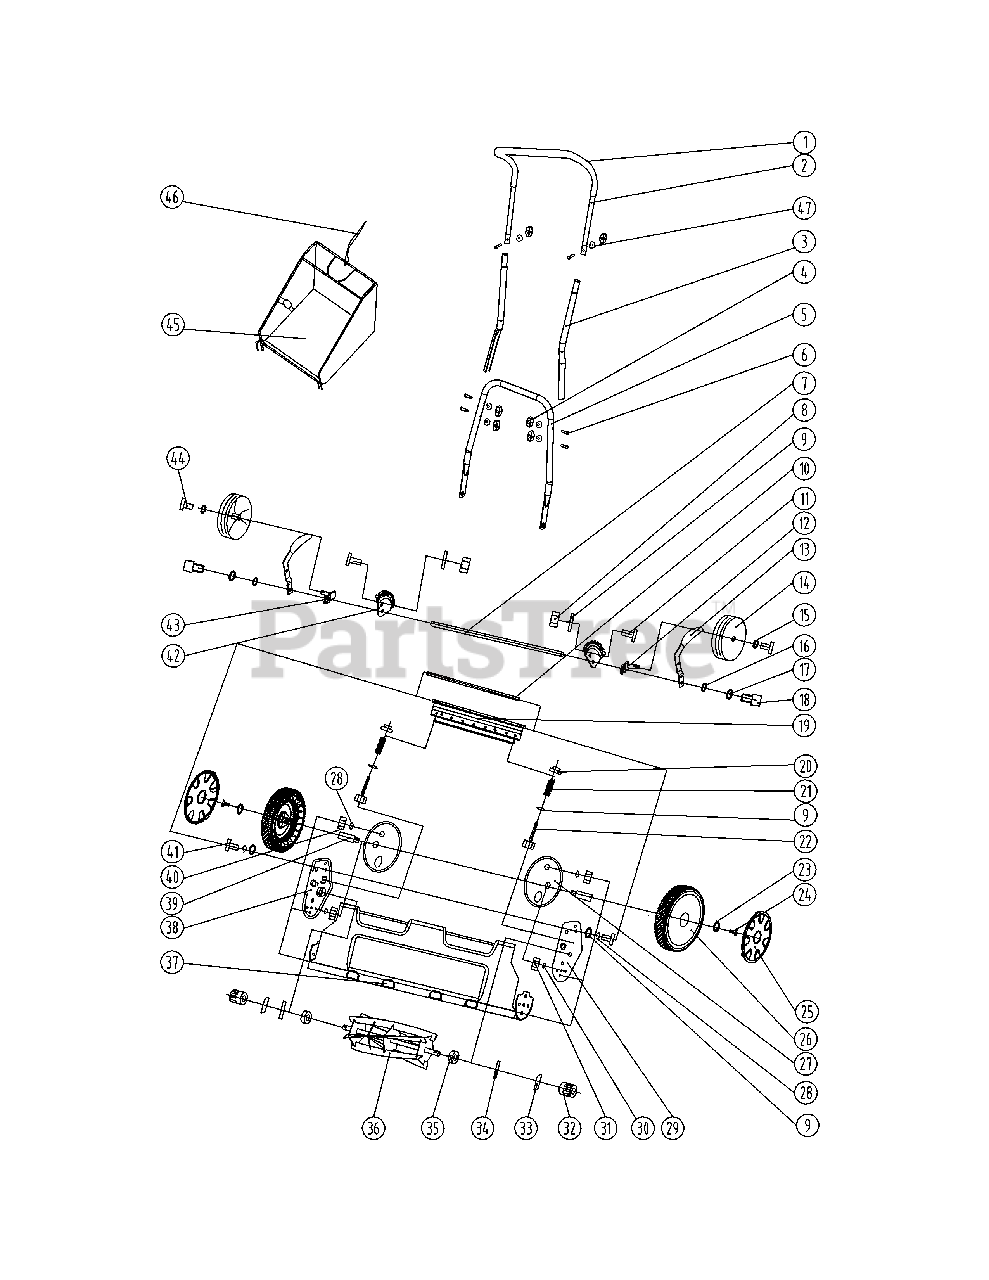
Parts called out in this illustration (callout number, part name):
1	Grip, Handle, 26 x 16 x 630
2	Handle, Upper
3	Handle, Middle
5	Handle, Lower, TBR16
5	Handle, Lower, TBR18
6	Bolt, M6x35gb/T12
7	Shaft, Rear, TBR16
7	Shaft, Rear, TBR18
8	Nut, M8, Gb/T6172.2
9	Washer, 17 x 8.2 x 1.2
10	Pin, TBR16
10	Pin, TBR18
11	Screw, M8-16gbt70.2
12	Bracket, Rear, LH,
13	Handle, Adjustment
14	Wheel, Rear
15	Washer, 17 x 8.2 x 1.2
16	Washer, Gb/T955
17	Washer, 20 x 13 x 1
18	Bolt, M8 x 24
19	Bracket, Lower Blade, TBR16
19	Bracket, Lower Blade, TBR18
20	Nut, M8 x 1
21	Spacer, 65mm, 17 x 4 x 48
22	Bolt, M8 x 1 x 65
23	Washer, 25 x 6.5 x 1.5
24	Bolt, M6x20, Gb/T5780
26	Wheel, Complete
27	Bracket, Black
28	Washer, Spacer, Gb/T7244
29	Bracket, Support, LH
30	Washer, 20x10.2x1.4
31	Nut, M10, Gb/T6172.2
32	Gear, 41mm, Pa66
33	Support, 19 x 10 x 5
34	Washer, 34 x 15.5 x 1
35	Bearing, 6002z
36	Blade, Roller, TBR16
36	Blade, Roller, TBR18
37	Shield, Deflector, TBR16
37	Shield, Deflector, TBR18
38	Bracket, Support, RH
39	Axle, Wheel, 19x65.5
40	Nut, M8, Gb/T6170
41	Bolt, M8x16gb/T5781
42	Bracket, Adjustment, 9 Tooth RH
42	Bracket, Adjustment, 9 Tooth LH
43	Bracket, Rear, RH
44	Bolt, M6x10 Gb/T5780
45	Grass Bag, TBR18
46	Strap, Grass Bag Hanger, TBR18
47	Saddle Washer
